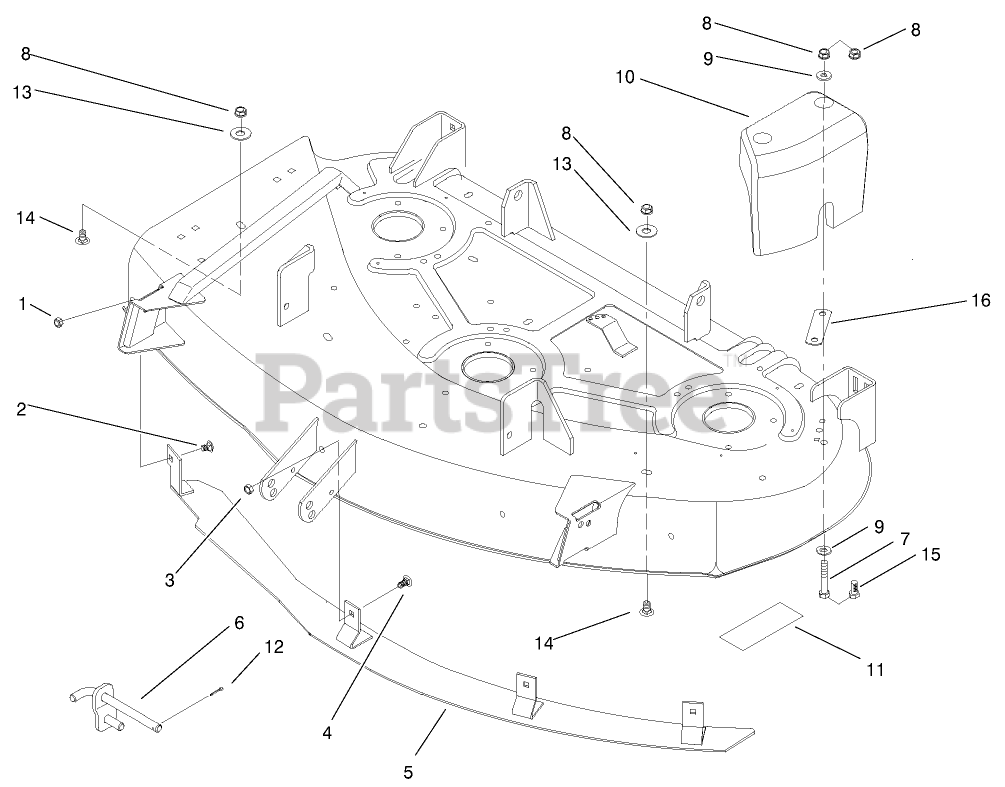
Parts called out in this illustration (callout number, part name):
1	NUT-LOCK, NI
2	BOLT-CARR
3	NUT-LOCK, NI
4	SCREW-CARR
6	ARM-LIFT, RH
7	SCREW-HH
8	NUT-LOCK, NI
9	WASHER-FLAT
10	WEIGHT-BAGGER, 44"
11	DECAL-DANGER
12	PIN-COTTER
13	WASHER-FLAT
14	SCREW-CARR
15	SCREW-HH
16	COVER
